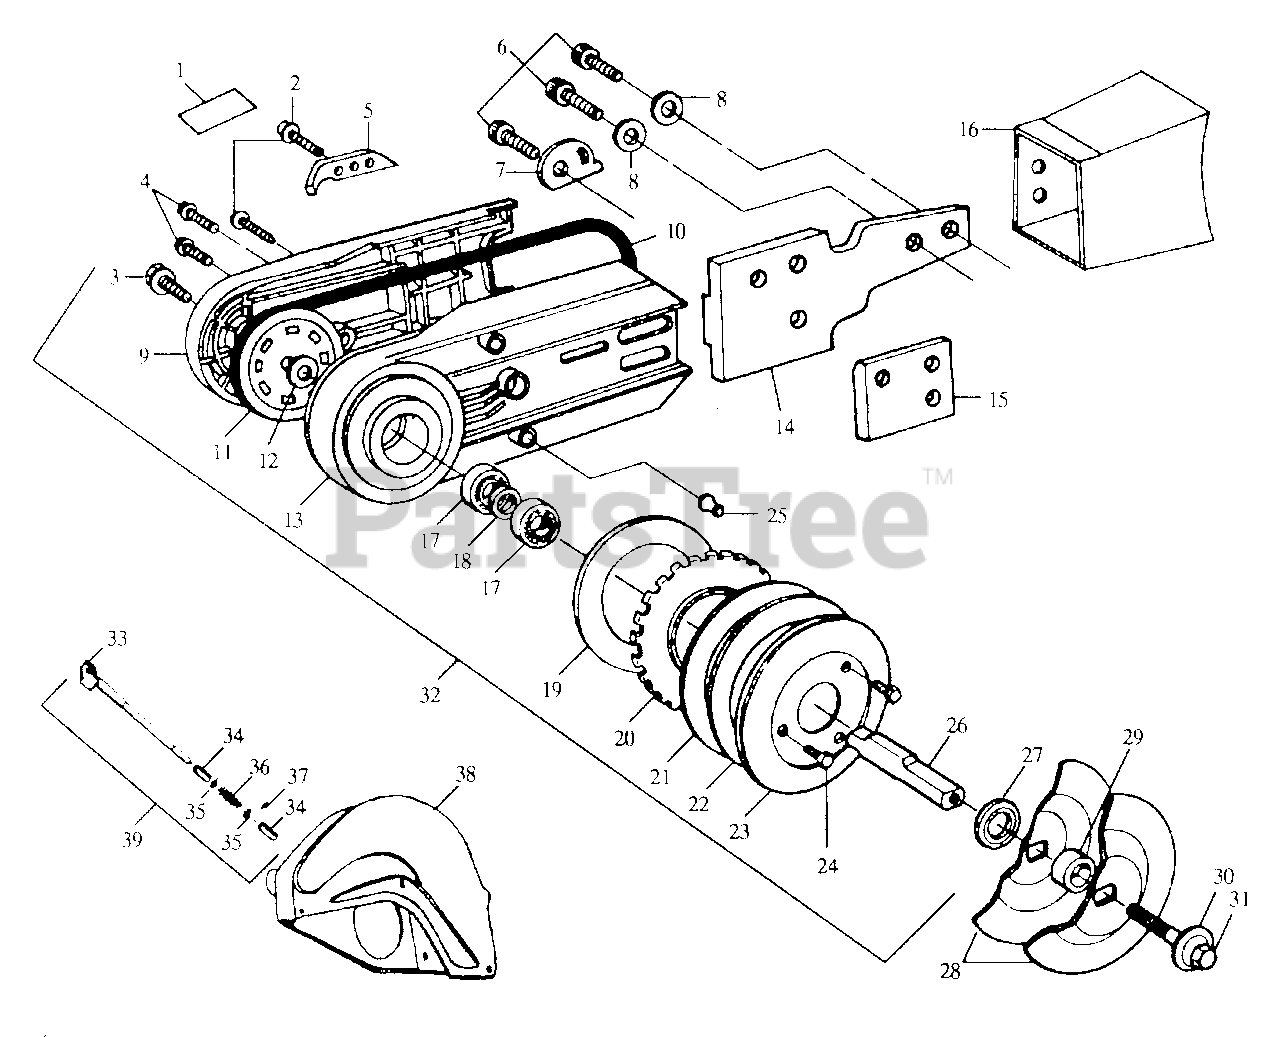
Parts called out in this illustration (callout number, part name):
1	Decal (not a serviceable part)
2	Screw
9	Spindle Arm Cover
11	Pulley
13	Spindle Arm
17	Ball Bearing
24	Bolt
26	Shaft
29	Sleeve
30	Washer
32	Cutting Arm Ass'y.
39	Guard Ass'y. Complete
